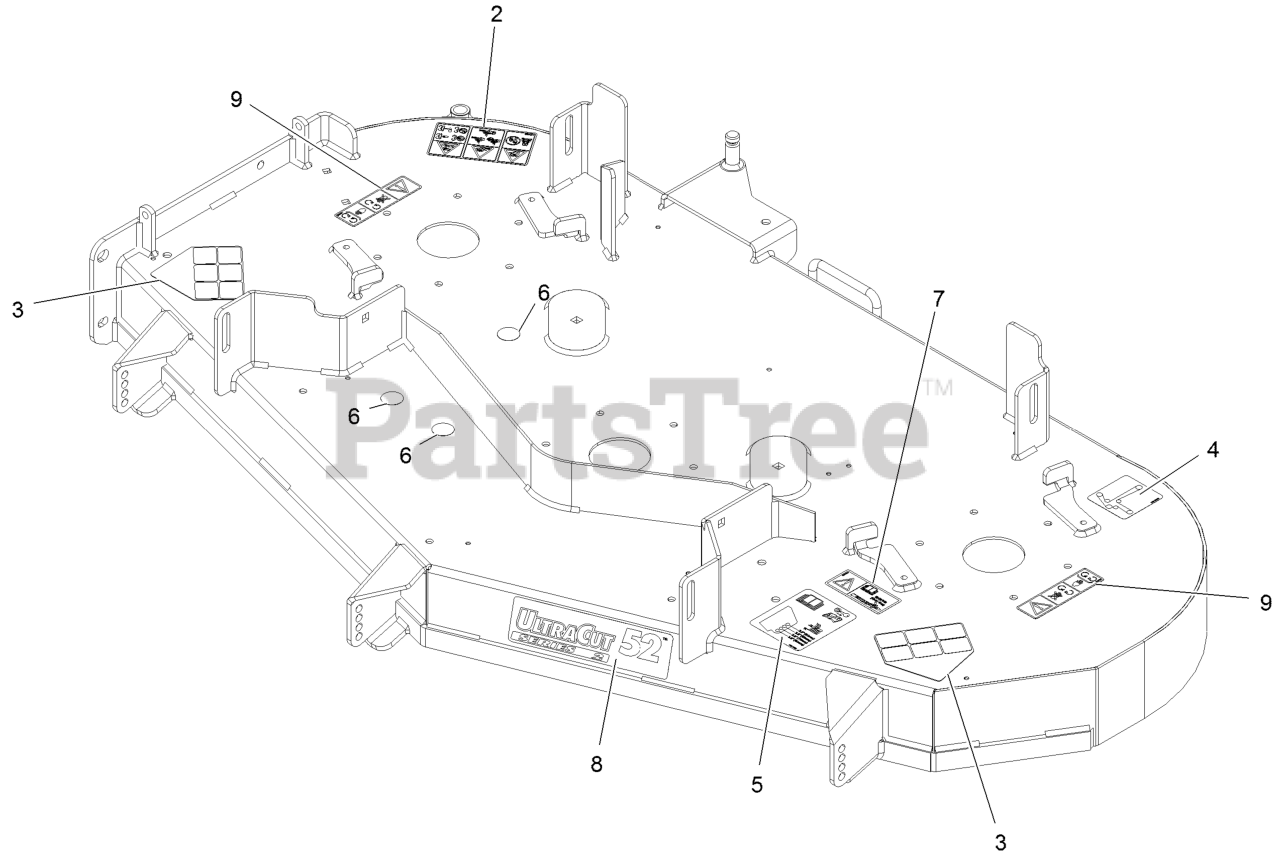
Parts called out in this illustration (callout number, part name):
2	DECAL-DANGER
3	DECAL-DANGER
4	DECAL-ROUTING, BELT
5	DECAL-ROLLER, ANTI-SCALP
6	DECAL-HOLE COVER
7	DECAL-BOLT TORQUE
8	DECAL-ULTRACUT 52 SERIES
9	DECAL-COVER, MISSING
